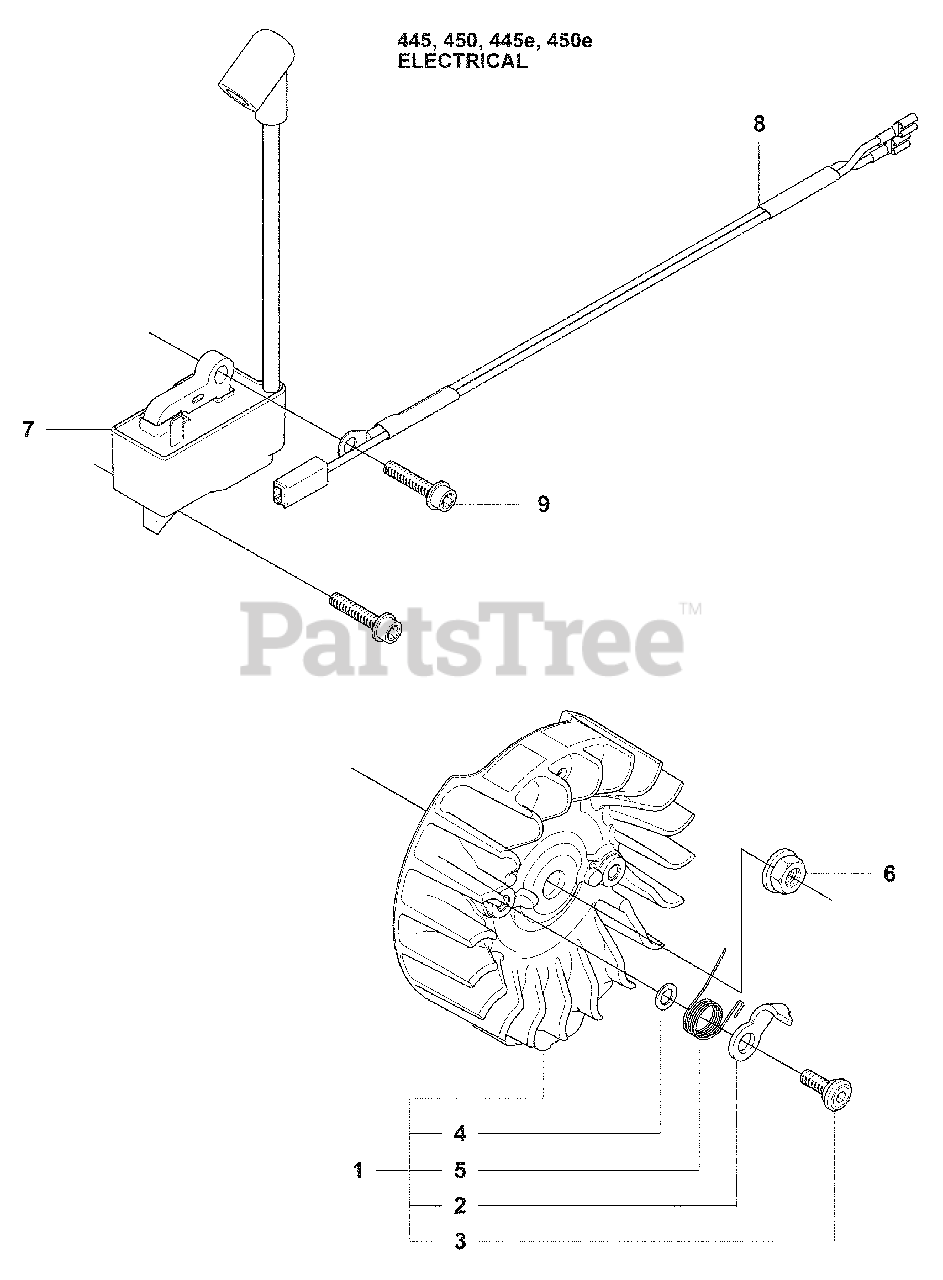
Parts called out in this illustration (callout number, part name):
1	Flywheel Assembly
2	Starter Pawl
3	Starter Catch Screw
5	Spring
6	Nut with Washer
7	Ignition Module, WALBRO MBU
8	Wiring Assembly
